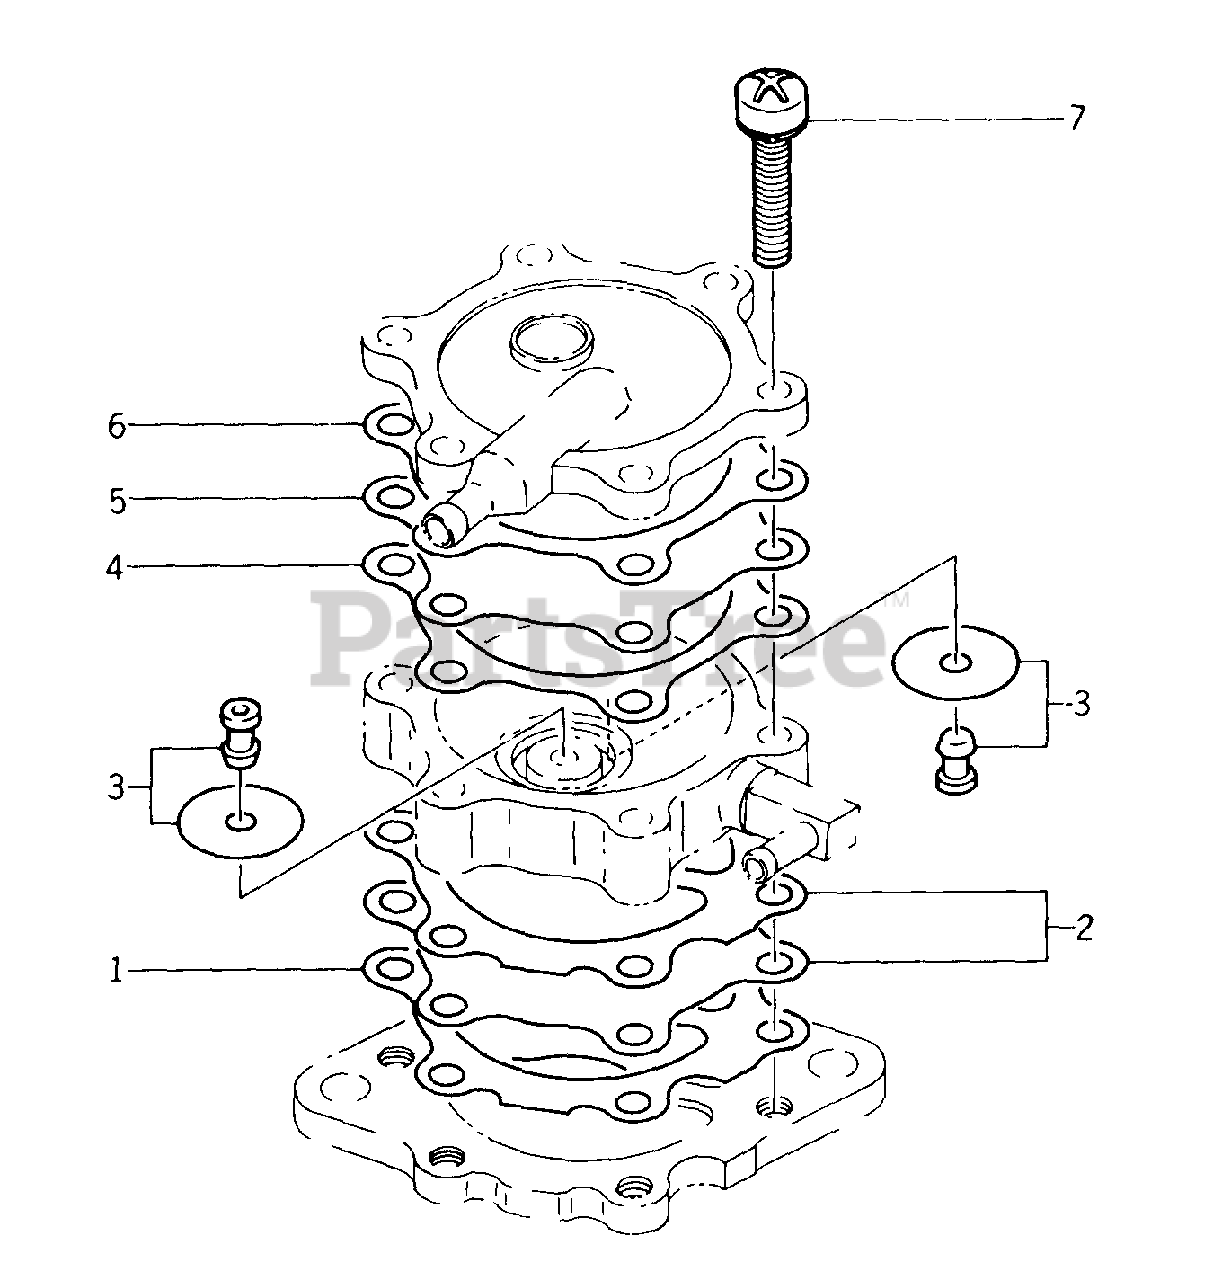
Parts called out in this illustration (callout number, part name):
1	GASKET
3	VALVE ASS'Y
5	DIAPHRAGM
